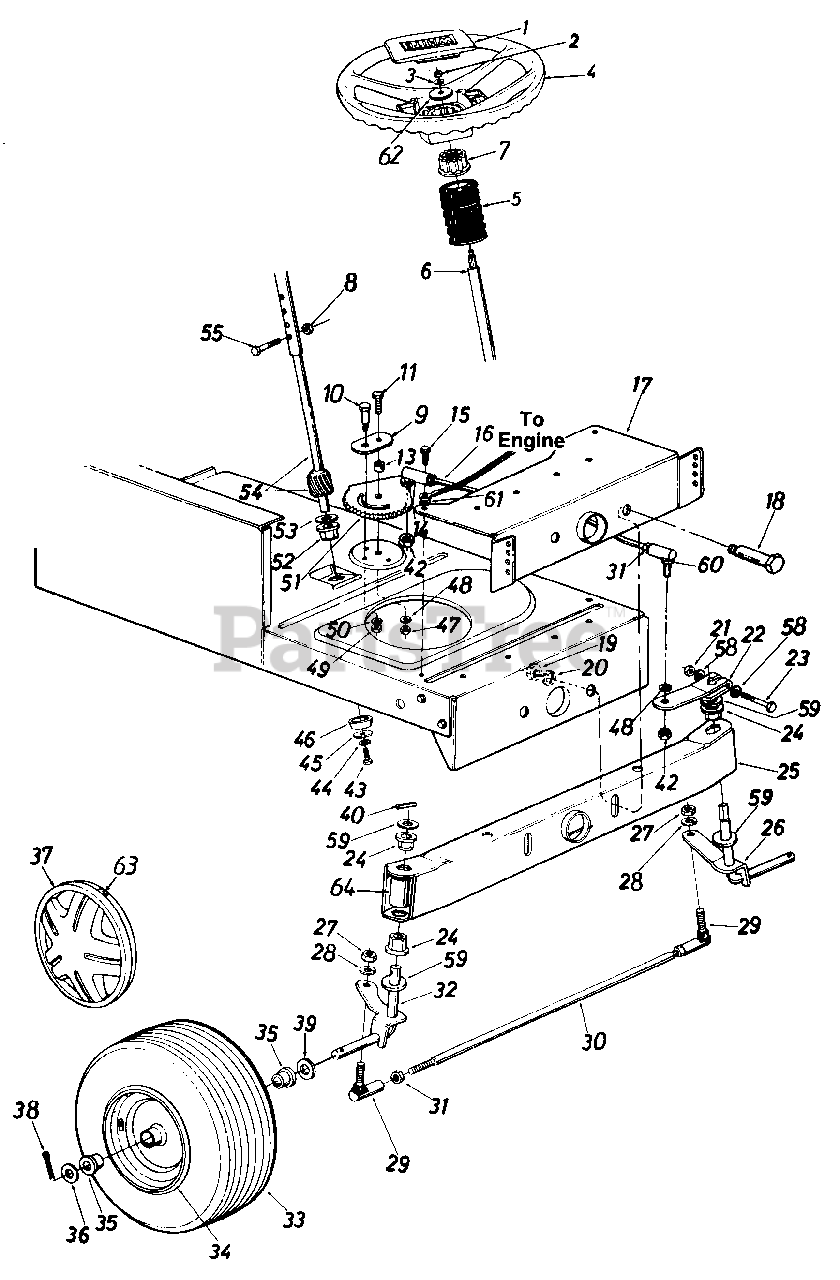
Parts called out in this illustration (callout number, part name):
1	Steering Wheel Insert
2	Hex L-Nut 5/16-24 Thd.
3	Belleville Wash. .345" I.D.
4	Steering Wheel
5	Steering Bellow
6	Steering Column Ass'y.
7	Steering Wheel Adapter
8	Hex L-Nut 1/4-20 Thd.
9	Retainer Plate
10	Shoulder Bolt .437" Dia. x .35" Lg. 5/16-18 Thd.
11	Hex Bolt 3/8-24 x 1.0" Lg. (Grade 5)
13	Spacer 380" l.D. x .625" O.D. x .227"
14	L-Wash. 318" I.D.
15	Hex Wash. Hd. Self-Tap Scr.
16	Steering Drag Link
17	Front Pivot Brkt.
18	Shoulder Bolt .48" Dia. x 2.04" Lg. 3/8-16 Thd.
19	Hex Nut 3/8-16 Thd.
20	L-Wash. 318" I.D.
21	Hex Cent. L-Nut 5/16-24 Thd.
22	Steering Arm Front Axle
23	Hex Bolt 5/16-24 x 2.00" Lg. (Grade 5)
24	Hex Flg. Brg. .634" I.D.
26	Front Axle Ass'y.-L.H.
27	Hex Nut 3/8-24 Thd.
28	L-Wash. 3/8" I.D.
29	Ball Joint 3/8-24 Thd.
31	Hex Jam Nut 3/8-24 Thd.
32	Front Axle Ass'y.-R.H.
33	Wheel Ass'y. Comp.
34	Front Wheel Rim Only
35	Flange Bearing (Bronze)
36	Fl-Wash. .635" I.D. x 1.59" O.D.
38	Cotter Pin 1/8" Dia. x 1.25" Lg.
39	Fl-Wash. .640" I.D. x .24" O.D.
40	Spring Roll Pin 1.12" Lg.
42	Hex Jam Nut 3/8-24 Thd.
43	Hex L-Bolt 5/16-18 x .62"
44	L-Wash. 5/16" 1..
45	Fl-Wash. .33" I.D. x 1.25" O.D.
46	Spacer (Plastic)
47	Hex Nut 3/8-24 Thd.
48	L-Wash. 3/8" I.D.
49	Hex Nut 5/16-18 Thd.
50	L-Wash. 5/16" I.D.
51	Steering Gear Segment
52	Hex Flg. Brg. .634 I.D.
53	Fl-Wash. (Hardened)
54	Steering Shaft Lower
55	Hex Bolt 1/4-20 x 1.31" Lg.
58	Wave Wash. .32" I.D. x .62"
59	Fl-Wash. (Hardened)
60	Drag Link Ball Joint 3/8-24 Thd.
61	Ext. L-Wash. 5/16" I.D.
62	Fl-Wash.
63	Spring Clip
64	Plastic Tube
